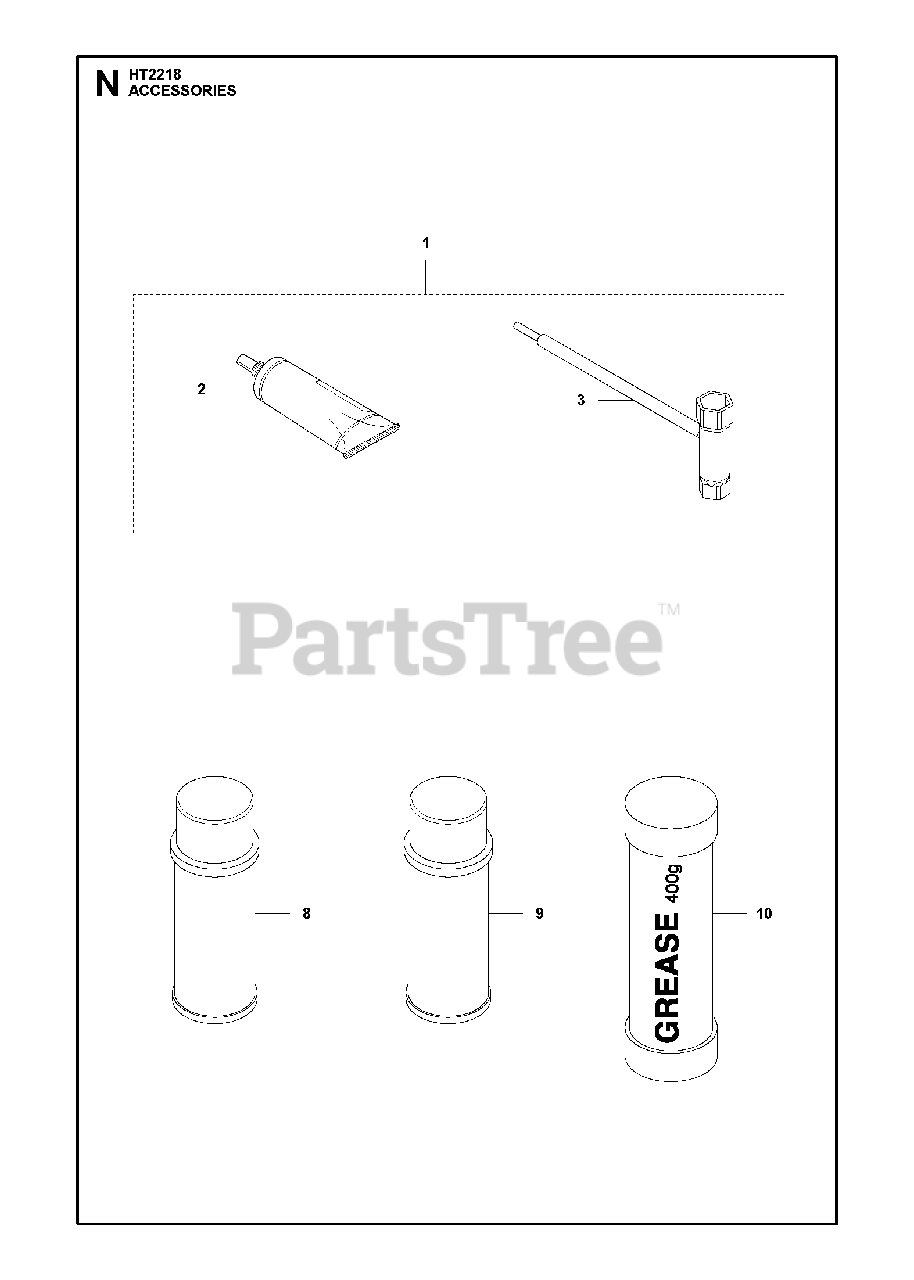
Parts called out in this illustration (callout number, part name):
1	ACCESSORY BAG
2	GREASE TUBE
3	COMBINATION WRENCH
10	GREASE 400 GRAMS
